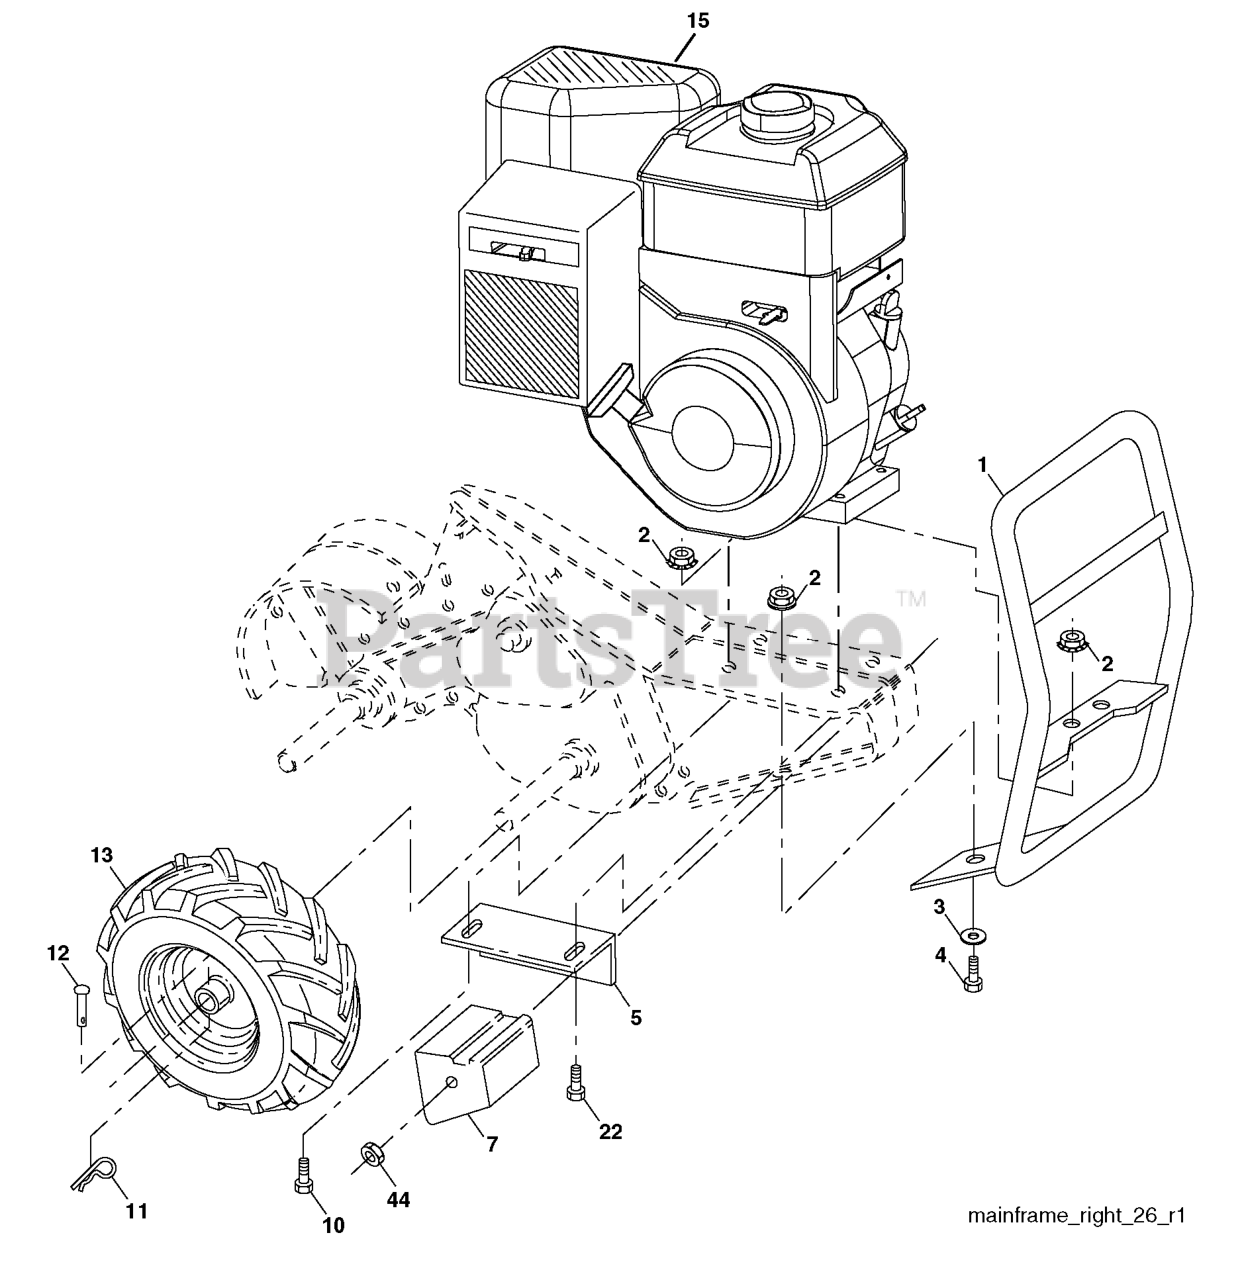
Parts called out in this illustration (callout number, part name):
1	RP.BUMPER.ASM.TILLER.
2	LOCKNUT-FLANGE 5/16-18
3	WASHER
4	BOLT
5	DNO BRACKET RH CRT
6	BOLT, HEX 5/16-18X1-3/4
7	COUNTERWEIGHT, RH
10	BOLT
11	RETAINER M
12	RIVET,DRILLED
13	TIRE.13X5-6.CHEVRON.TILLER
